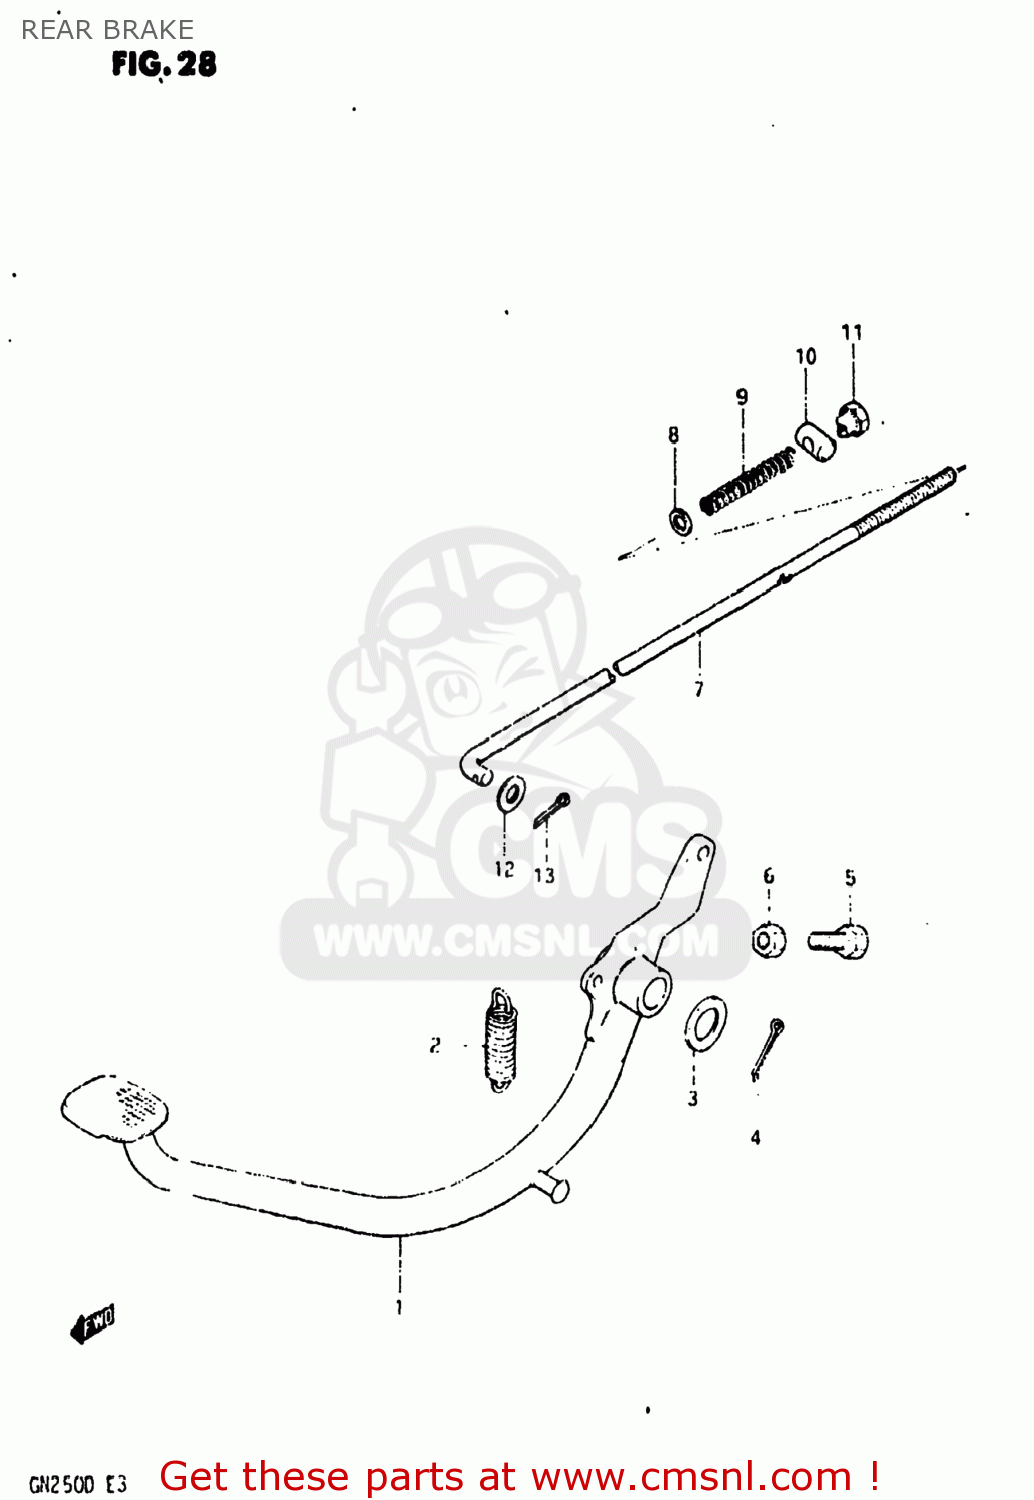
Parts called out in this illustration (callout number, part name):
1	PEDAL,BRAKE
2	SPRING
3	WASHER(15.5X26X2.3)
4	COTTER PIN
5	SCREW(6X23)
6	NUT
7	ROD ASSY,RR BRAKE
8	WASHER
9	SPRING
10	PIN
11	NUT
12	WASHER
13	PIN 20X20
